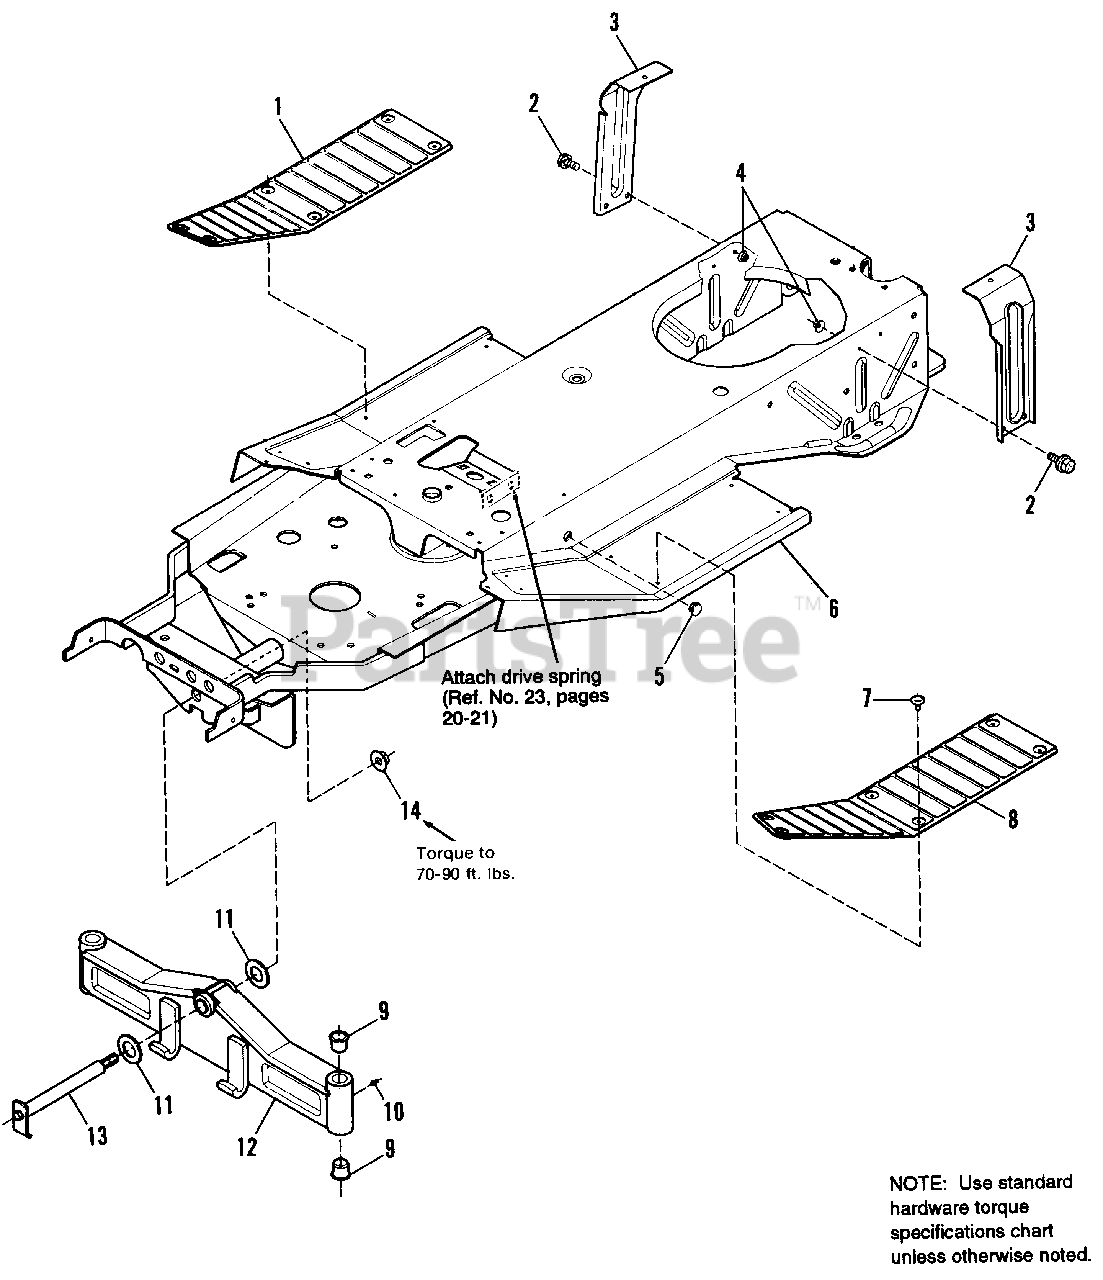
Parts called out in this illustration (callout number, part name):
1	PAD, Footrest, R.H.
2	CAPSCREW, Hex, Flange, Whizlock, 3/8-16 x 1
3	SUPPORT, Seat
4	NUT, Hex, Esna Lock, 3/8-16
6	FRAME ASSY.
7	FASTENER, Panel (Qty. 12 on Hydro)
8	PAD, Footrest, L.H.
10	GREASE, Fitting
11	WASHER, Special
12	AXLE ASSY., Front
13	AXLE PIVOT ASSY.
14	NUT, Hex, Full, Lock, 3/4-16
